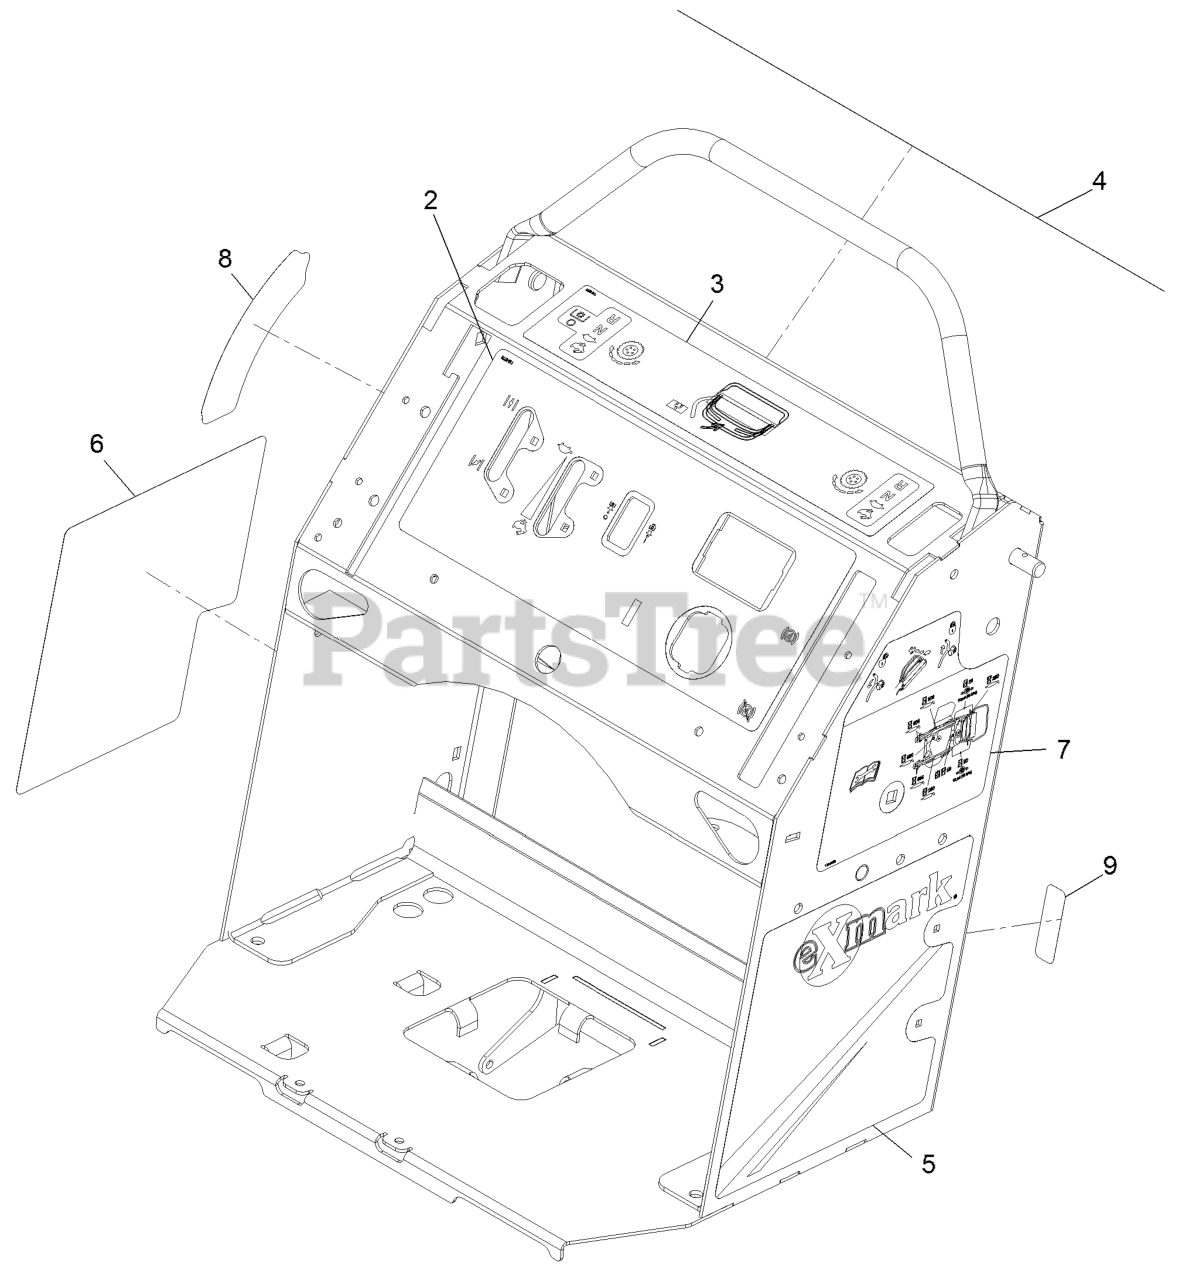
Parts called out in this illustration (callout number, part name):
2	DECAL-CONTROL PANEL
3	DECAL-MOTION CONTROL
4	DECAL-WARNING
5	DECAL-LH PANEL
6	DECAL-RH PANEL
7	DECAL-SERVICE AID
8	DECAL-HEIGHT OF CUT
9	DECAL-FUSE
